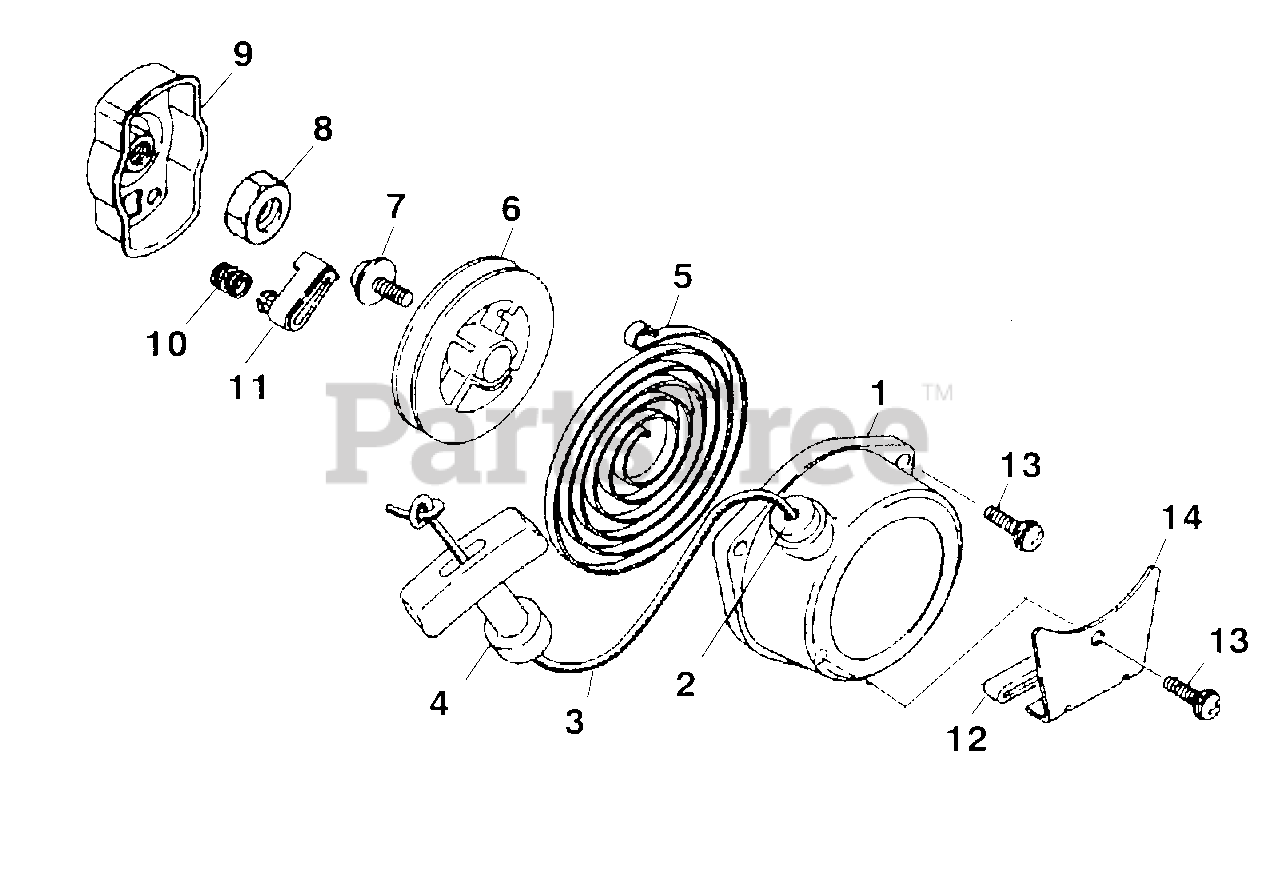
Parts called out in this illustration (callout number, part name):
1	STARTER ASSY
3	ROPE, STARTER
4	KNOB, STARTER
5	SPRING, REWIND
7	SCREW & WASHER
8	NUT
9	PULLEY ASSY, STARTER
10	SPRING, RETURN
11	RATCHET
13	SCREW & WASHER
14	BRACKET
